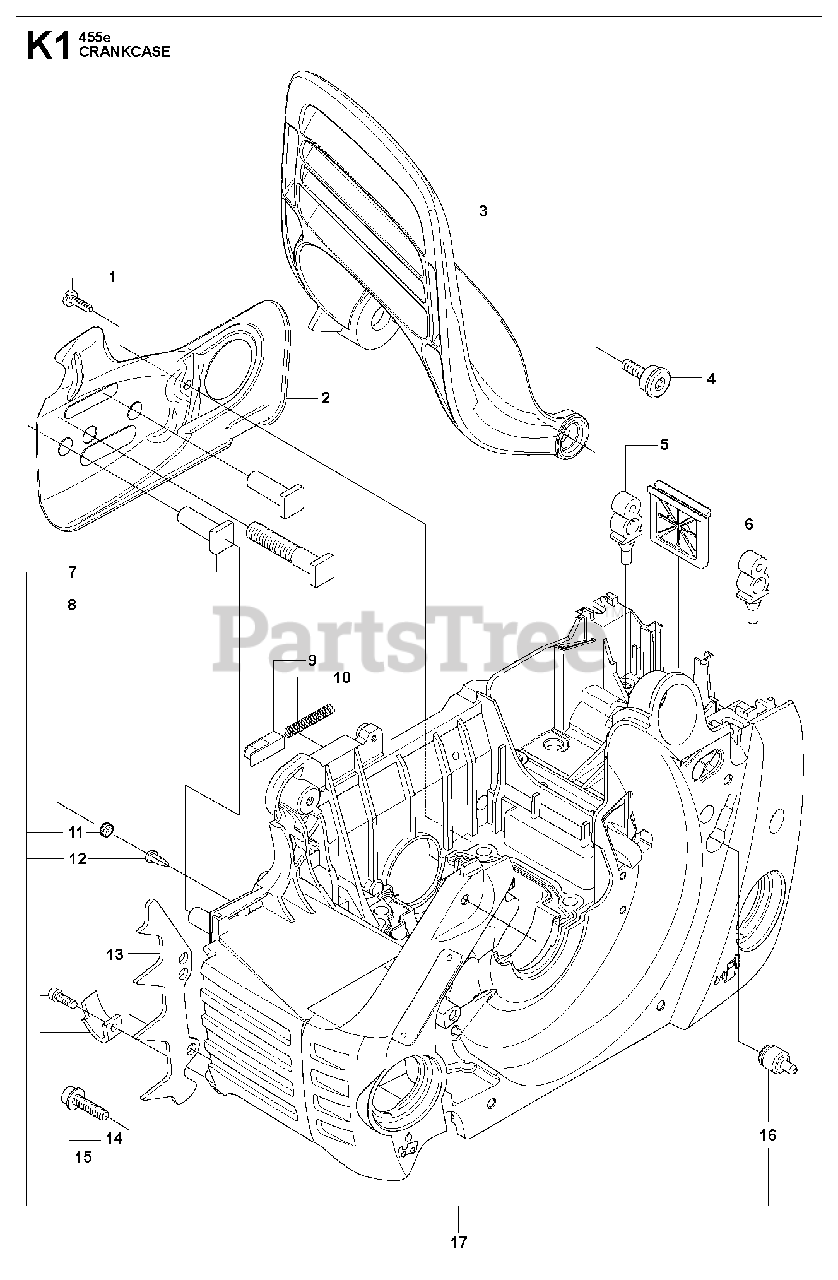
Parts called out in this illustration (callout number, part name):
3	HAND GUARD
4	SCREW, HAND GUARD
7	GUIDE BOLT (X2)
8	BOLT
10	LOCK SPRING
11	PLUG
12	VALVE-CHECK (DUCKBILL)
13	FELLING DOG
14	SCREW IHSCFT
15	CHAIN CATCHER
16	FUEL TANK VENT
17	CRANKCASE ASSY
